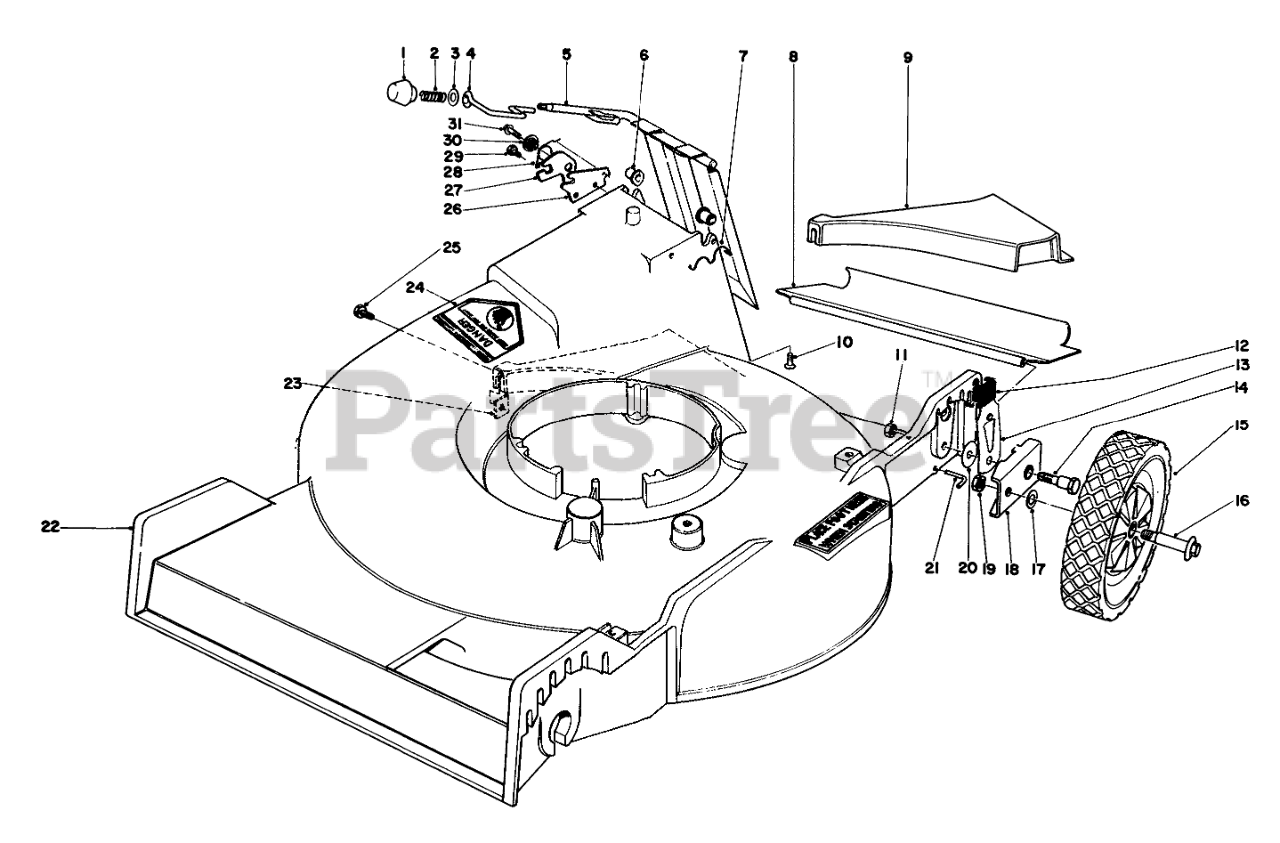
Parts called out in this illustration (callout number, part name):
2	COMPRESSION SPRING
3	WASHER-FLAT
4	DOOR LATCH
5	DOOR HANDLE WA
6	Bushing
7	DOOR RETAINER
8	REAR SAFETY SHIELD
9	REAR INSERT
10	SCREW-HH
11	Nut
12	KNOB-ARM
13	SPRING ARM ASM HP
14	PIVOT SCREW
15	Lever-Valve
16	Wheel Bolt
17	WASHER
18	Pivot Arm
19	Nut
20	PIVOT WASHER
21	ROD-SHIELD
22	Housing (Incl. Ref. #24)
23	SPECIAL NUT
24	DECAL-DANGER
25	SCREW THD 1/4 20 5/8
26	DOOR LATCH PLATE
27	Latch-Door
28	TORSION SPRING
29	SCREW-HWH
30	Latch Spacer
31	Screw
